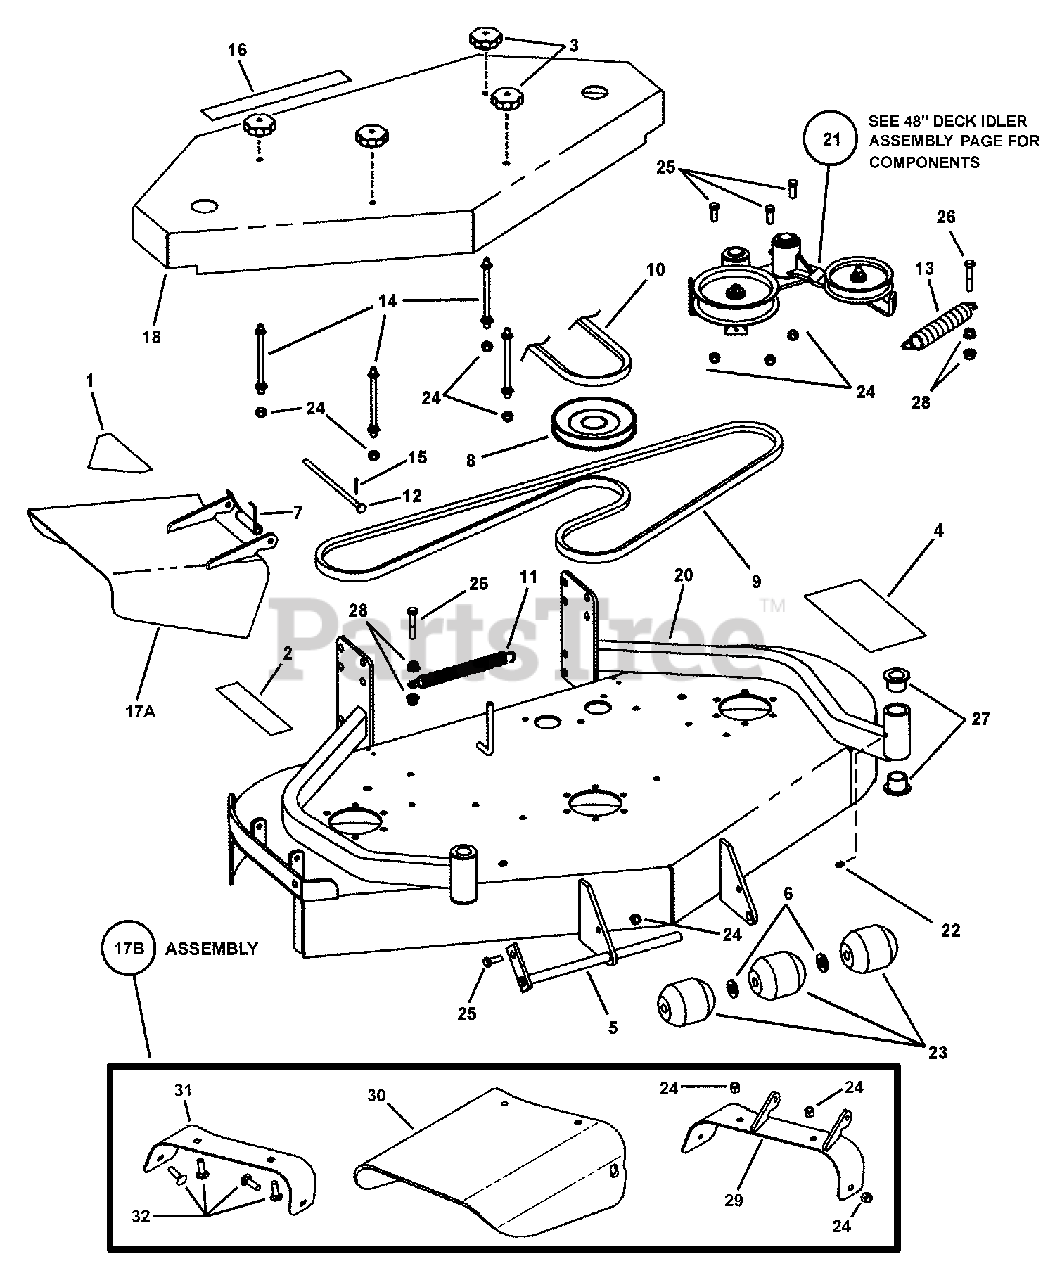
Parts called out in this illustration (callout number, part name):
1	DECAL, Warning (CPSC Cut Finger)
2	DECAL, Warning
2	DECAL, Danger, Guard, Catcher
3	KNOB, Hood (5/16-18 thread)
4	DECAL, Caution- Operator Instruction
5	PIVOT, Roller Pin (Weldment)
6	WASHER, 5/8" Flat
7	SPRING, Chute
8	PULLEY, Driven 5-3/4" O.D.
9	V-BELT, Secondary 48" (113" Long)
10	V-BELT, Primary 48" (66" Long)
11	SPRING, Primary
12	HINGE PIN, Chute
13	SPRING, Idler
14	STANDOFF, 4-1/2" Long
15	COTTER PIN, 3/32 x 1"
16	DECAL, SNAPPER Pro w/Trademark
16	DECAL, SNAPPER Pro
17A	DEFLECTOR, 48" Chute (Weldment)
17B	ASSEMBLY, Discharge Chute
18	48" COVER
20	WELDMENT, 48" Deck (Fixed Height)
21	ASSEMBLY, Idler - 3 Spindle Deck
22	FITTING, 1/4-28 Straight Lube
22	FITTING, Lube Press-In
23	ROLLER, Low Density Polyethylene
24	NUT, 3/8-16 HEX NYLON LOCK
25	BOLT, 3/8-16 X 1" GD5 CZ
26	BOLT, 3/8-16 X 2, GD5, CZ
27	BUSHING, Caster
28	NUT, 3/8-16 HEX SERRATED FLANGE
29	WELDMENT, 48" Chute
30	CHUTE, Rubber
31	DEFLECTOR, Bottom
32	BOLT, 3/8-16 x 1-1/4" Square Neck Carriage, GR 5
